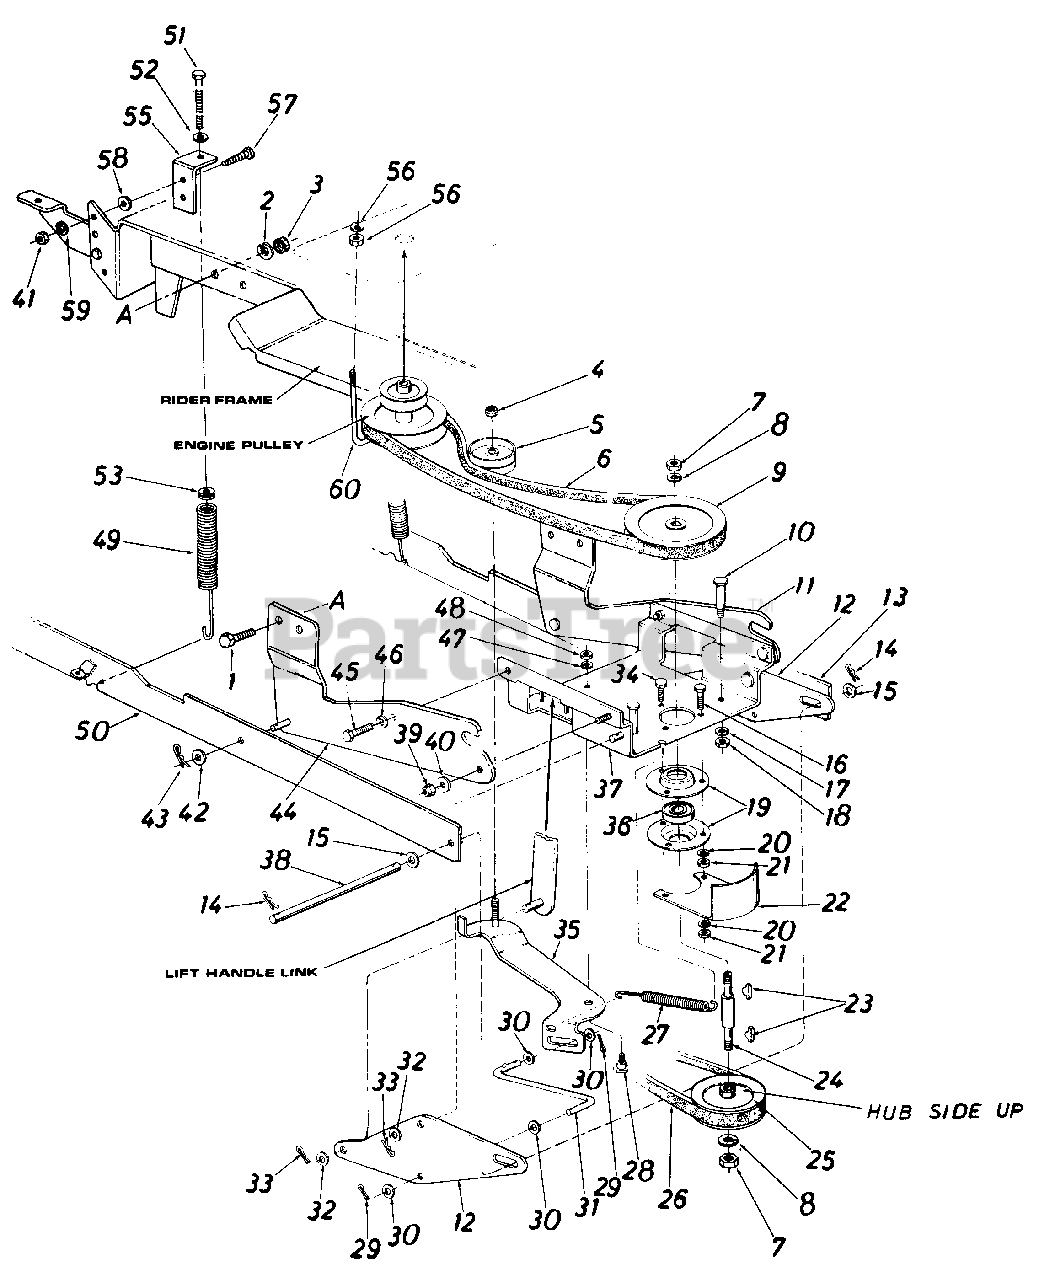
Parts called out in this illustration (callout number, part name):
1	Hex Scr. 1/4-28 x .75" Lg. Grade 5
2	L-Wash. 1/4" Scr.*
3	Hex Nut 1/4-2 Thd.*
4	Hex Ins. Jam Nut 3/8-24 Thd.
5	Flat Idler 3.25" O.D.
6	"V"-Belt 1/2 x 49" Lg.
7	Hex Jam Nut 5/8-11 Thd.
8	L-Wash. 5/8" I.D.*
9	6.50" O.D. x 5/8 Pulley
10	Shoulder Screw
11	Channel Supporting Brkt.- R.H.
12	Linkage Brkt.
13	Linkage Arm Ass'y. -R. H .
14	Intern. Cotter Pin .500" D ia.*
15	Fl.-Wash.
16	Hex Scr. 5/16-18 x 1.25" Lg.*
17	L.-Wash. 3/8" Scr.*
18	Hex Nut 3/8-16 Thd.*
19	Bearing Housing
20	L.-Wash. 5/16" Scr.*
21	Hex Nut 5/16-18 Thd.*
24	Pulley Spindle
25	4.00 O.D. x 5/8 Pulley
26	"V"-Belt 1/2 x 85.2" Lg.
27	Extension Spring
28	Shoulder Screw
29	Cotter Pin 3/32" Dia. x 1.00*
30	Fl-Wash.
31	Control Rod
32	Fl-Wash.
33	Inter. Cotter Pin .500" Dia.*
34	Hex Sems Scr. 5/16-18 x .75" Lg.*
35	Clutch Idler Brkt. Ass'y.
36	Ball Bearing
37	Channel Ass'y.
38	Lift Handle Shaft
39	Hex Ins. L-Nut 3/8-16 Thd.
40	F l.-Wash.
41	Hex Nut 1/4-2 Thd.*
42	F l.-Wash.
43	Intern. Cotter Pin .500" Dia*
44	Channel Supporting Brkt.- L.H.
45	Hex Scr. 3/8-16 x 1.00"
46	L.-Wash. 3/8" Scr.*
47	L.-Wash. 5/16" Scr.*
48	Hex Nut 5/16-18 Thd.*
49	Helper Spring
50	Linkage Arm Ass'y. - L.H.
51	Hex Scr. 5/16-18x 2.0" Lg Special
52	Fl.-Wash. 5/16" Scr.*
53	Spring Insert
57	Hex Bolt 1/4-20 x .75" Lg.*
58	Fl.-Wash..264" I.D.
59	L.-Wash. 1/4" I.D.*
60	J-Bolt 5/16-18
